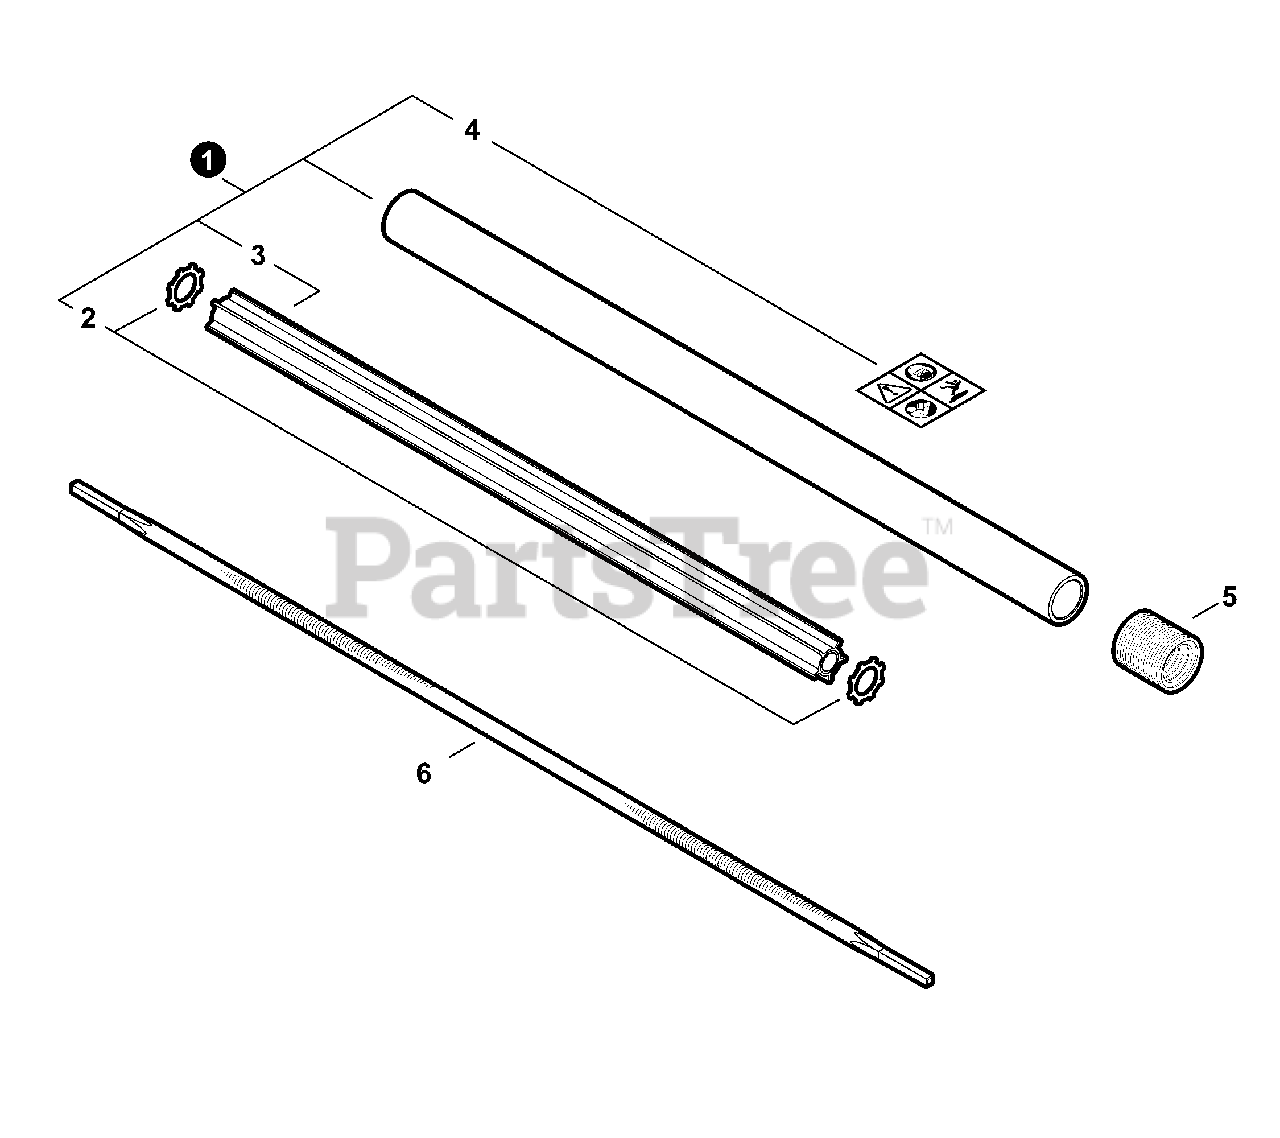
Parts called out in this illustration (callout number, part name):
1	MAIN PIPE ASSY
4	LABEL, CAUTION
5	TUBE, FLEXIBLE
6	DRIVESHAFT - FLEXIBLE
